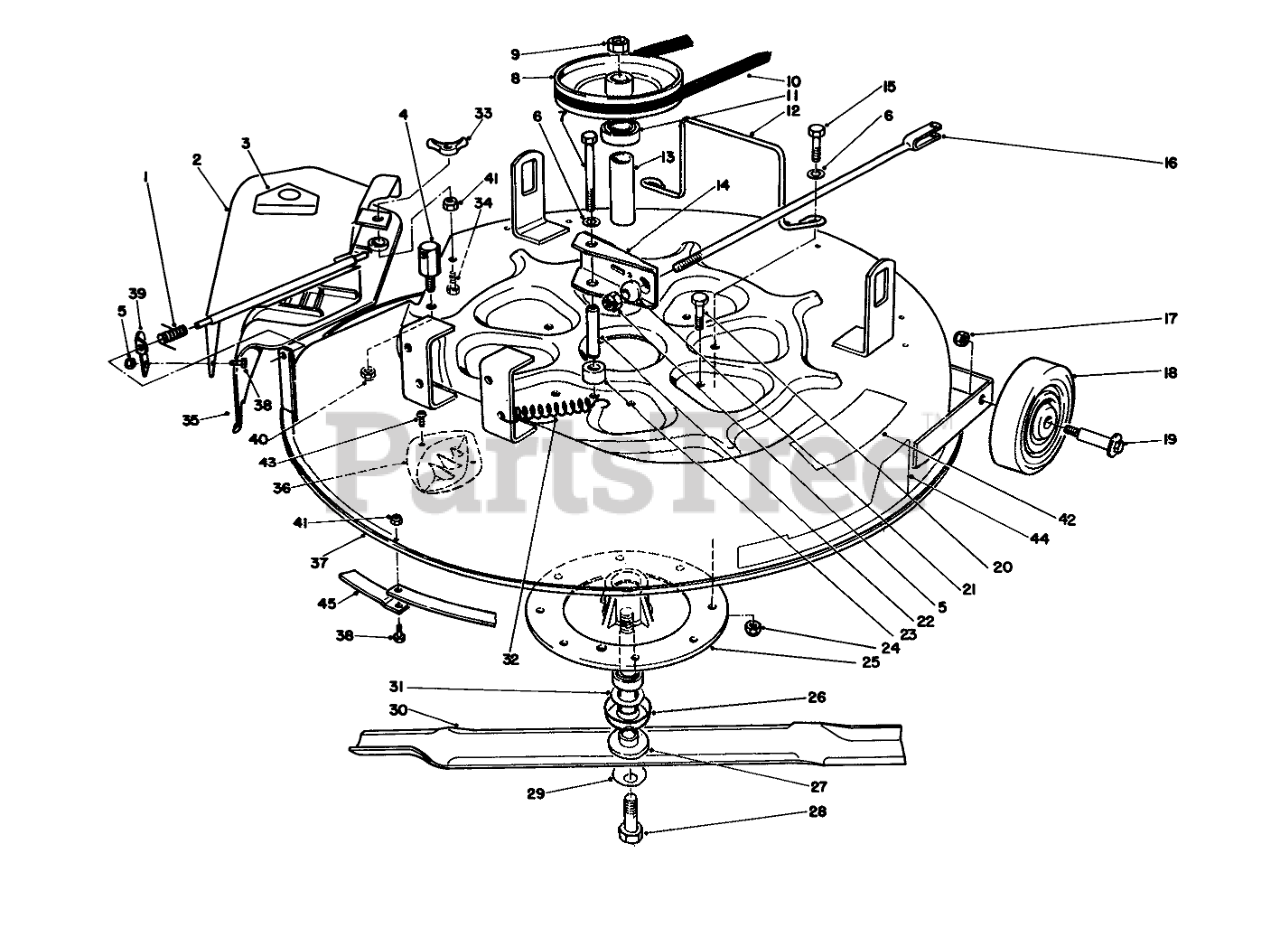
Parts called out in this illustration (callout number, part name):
1	SPRING
2	Deflector (Incl. Ref. #3)
3	DECAL-DANGER
4	POST-PIVOT
5	NUT-HEX
6	WASHER-PLAIN
7	SCREW-HH
8	PULLEY-DECK
9	NUT-HEX
10	V-Belt
11	BEARING-BALL
12	GUIDE-DECK BELT
13	SPACER-BEARING
14	DECK BRAKE ASSEMBLY
15	SCREW-HH
16	DECK BRAKE ROD WA
17	NUT-LOCK, NI
18	WHEEL-DECK
19	BOLT-WHEEL
20	SCREW-HH
21	BALL-SWIVEL, STOP
22	POST-BRAKE MTG
23	SPACER-DECK BRAKE
24	NUT-LOCK, NI
25	CASTING-SPINDLE
26	SHIELD-BEARING
27	SHAFT-SPINDLE
28	SCREW-HH
29	WASHER-BELLEVILLE
30	Blade
31	SPACER
32	SPRING-EXTENSION
33	Nut-Wing
34	SCREW-HHF
35	COVER- 25" (W/KICKER)
36	KICKER
37	Deck
38	SCREW-HH
39	Bracket-Detector
40	NUT-LOCK, NI
41	NUT-LOCK, NI
42	DECAL - DANGER
43	#8 X .625" PHILPS PAN H
44	DECAL - RECYCLER
45	Ring-Deck
